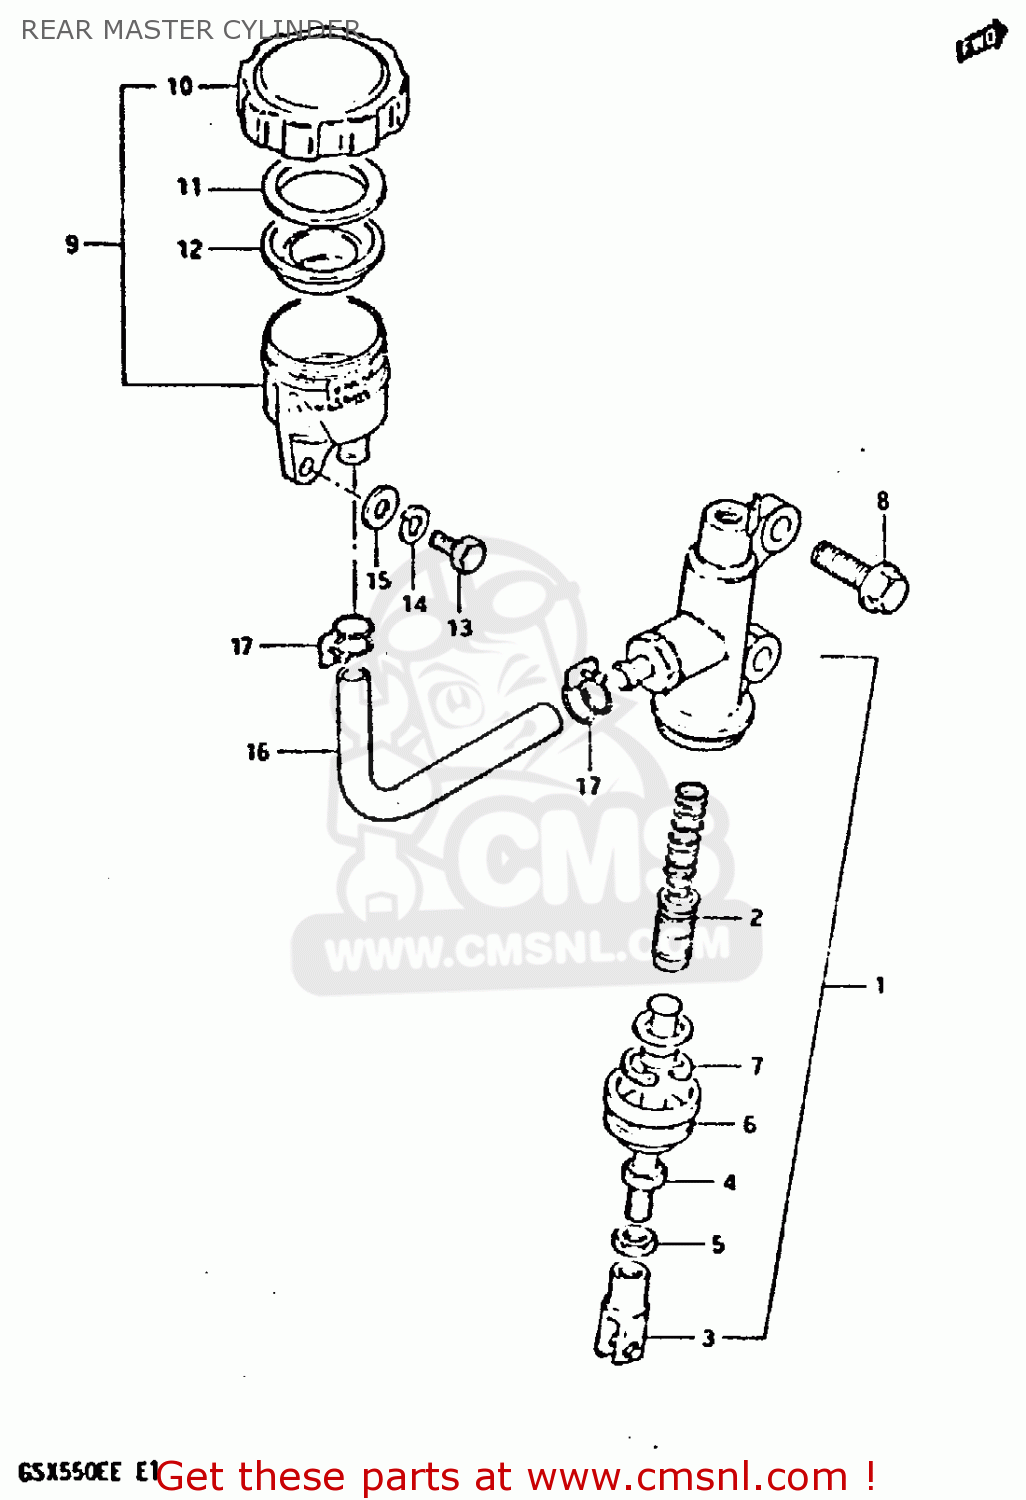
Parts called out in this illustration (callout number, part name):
1	CYLINDER ASSEMBLY,REAR MASTER
2	PISTON/CUP SET
3	YOKE
4	ROD,PUSH
5	NUT,MASTER CYLINDER
6	BOOT
7	CIRCLIP
8	BOLT
9	TANK ASSEMBLY,RESERVOIR
10	CAP
11	PLATE,DIAPHRAGM
12	DIAPHRAGM
13	BOLT, UPPER
14	LOCK WASHER
15	WASHER
16	HOSE,RESERVOIR TANK
17	CLAMP
